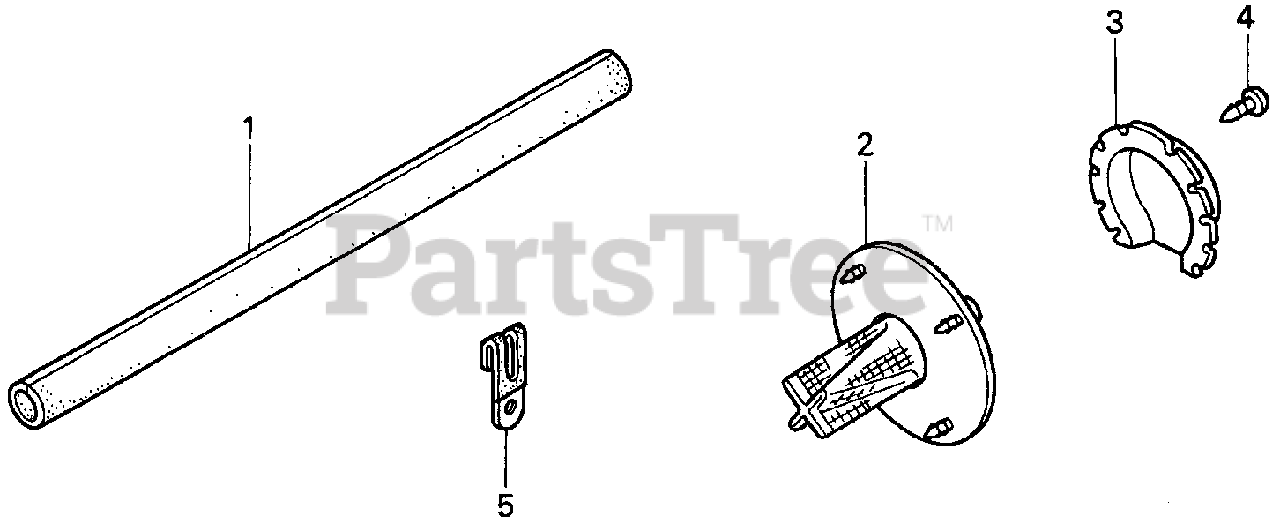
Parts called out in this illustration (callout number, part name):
1	RUBBER, SUPPORTER
2	ARRESTER, SPARK (SIDE)
3	DEFLECTOR KIT, EX.
4	SCREW (NELSON) (SCREW UNAVAILABLE SEPARATELY. ORDER DEFLECTOR KIT.)
5	CLIP, CABLE
